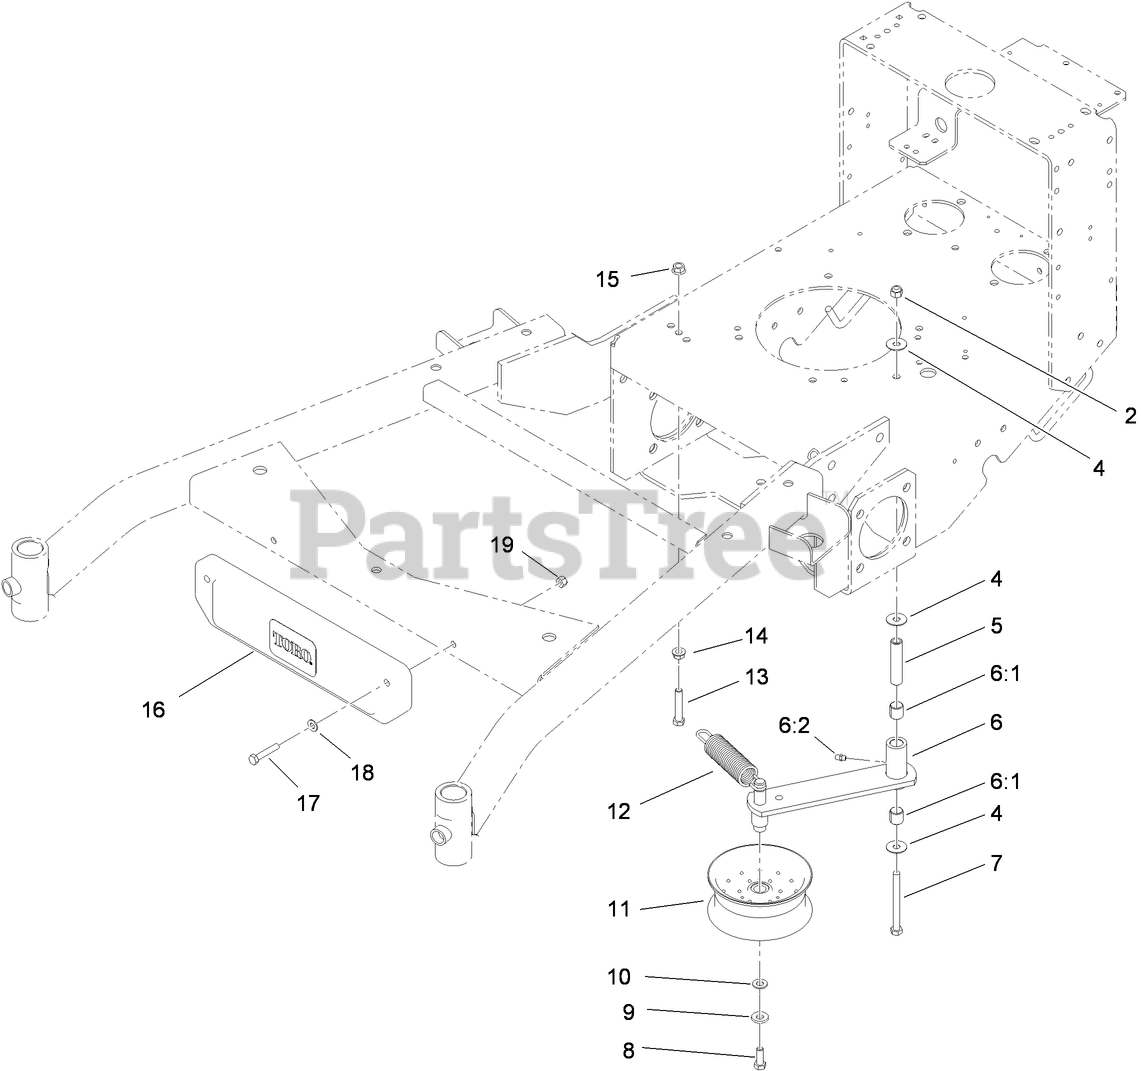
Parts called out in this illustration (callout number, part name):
2	NUT-LOCK, NI
4	WASHER
5	TUBE-IDLER
6	IDLER ARM ASM
6:1	SLEEVE-BEARING
6:2	FITTING-GREASE
7	SCREW-HH
8	SCREW-HH
9	WASHER-BELLEVILLE
10	WASHER-FLAT
11	PULLEY-IDLER
12	SPRING-EXTENSION
13	SCREW-HH
14	NUT-HHF, WHIZ
15	NUT-HF
16	WEIGHT-CAST
17	SCREW-HH
18	WASHER-PLAIN
19	NUT-LOCK, NI
